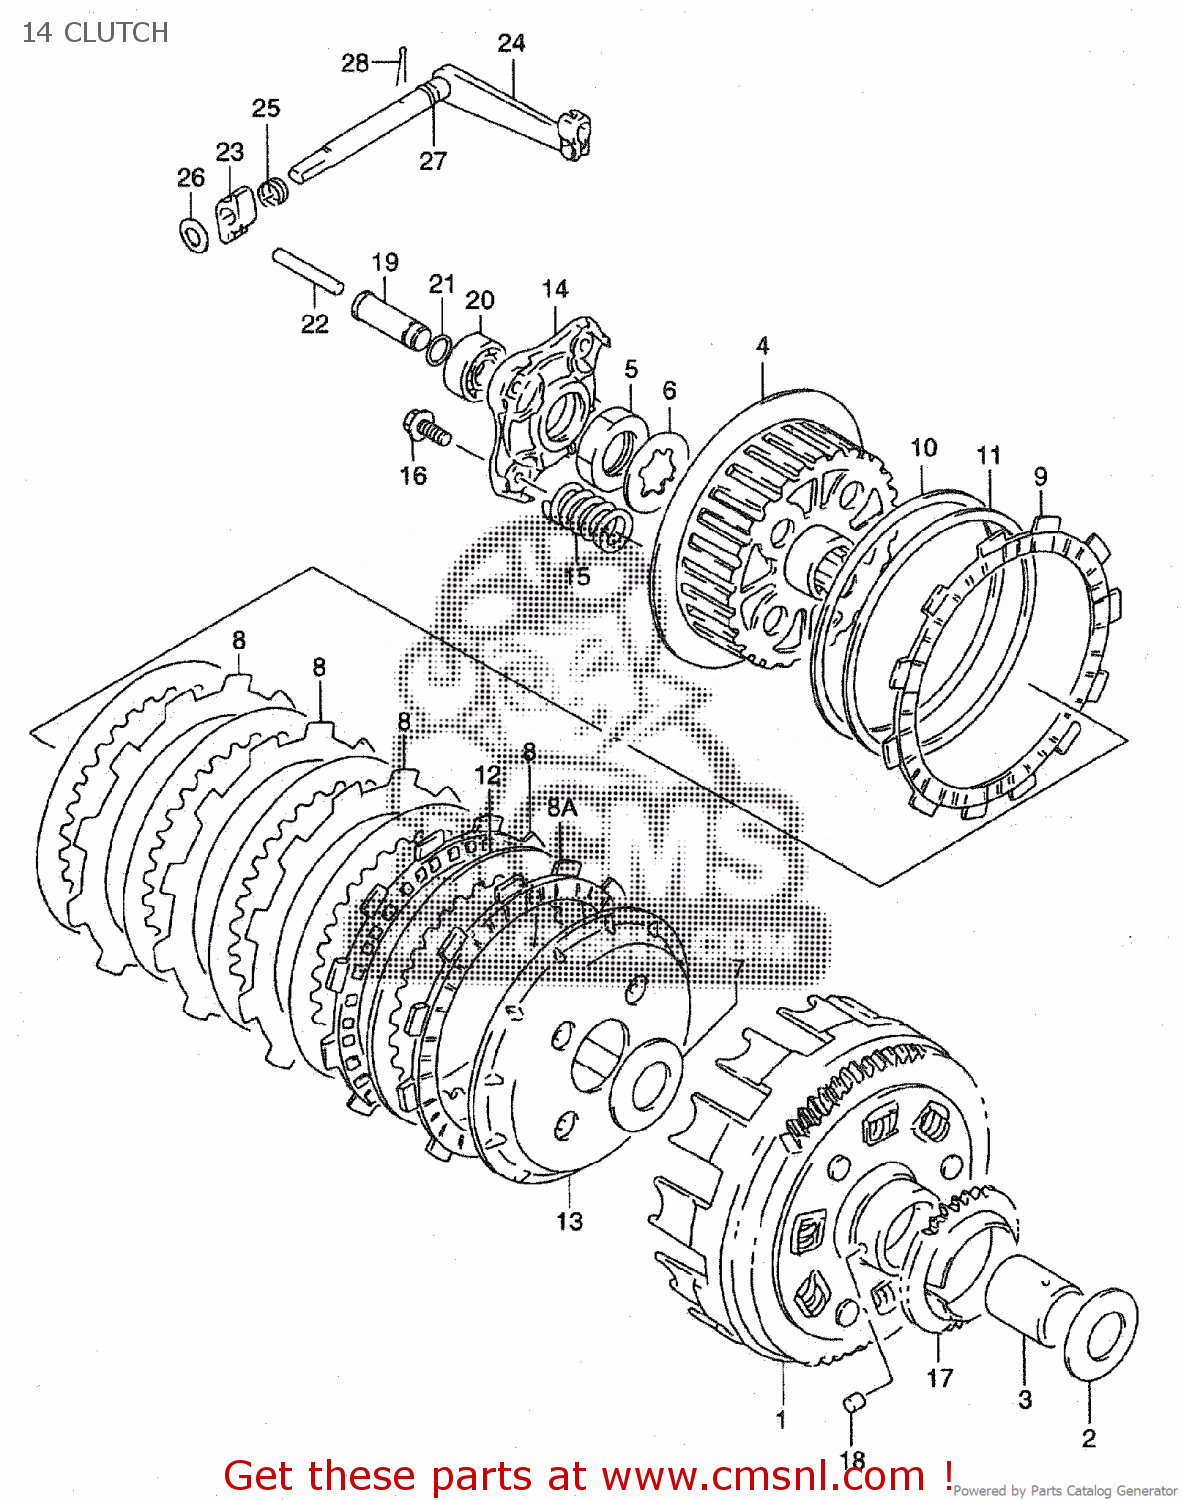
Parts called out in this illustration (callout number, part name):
1	GEAR ASSY,PRI DRIVEN(NT:71)
2	WASHER
3	SPACER(22X28X32.5)
4	HUB,CLUTCH SLEEVE
5	NUT
6	WASHER,LOCK
7	WASHER
8	PLATE,CLUTCH DRIVE NO.1 (NAS)
8A	PLATE,CLUTCH DRIVE (NAS)
9	PLATE,CLUTCH DRIVE(T:3.5) (NAS)
10	SEAT,WAVE WASHER(T:1.4)
11	WASHER
12	PLATE,CLUTCH DRIVEN(T:1.6) (NAS)
13	DISC,CLUTCH PRESSURE
14	PLATE,RELEASE
15	SPRING
16	BOLT
17	GEAR,ENG OIL PUMP DRIVE
18	PIN(6X6)
19	PIECE,CLUTCH PUSH
20	BEARING(12X28X8)
21	O RING(D:1.9,ID:8.6)
22	ROD,CLUTCH PUSH
23	CAM,CLUTCH RELEASE
24	ARM ASSY,CLUTCH RELEASE
25	SPRING
26	SHIM(10X14X1)
27	O RING(D:1.9,ID:6.8)
28	PIN 20X20
